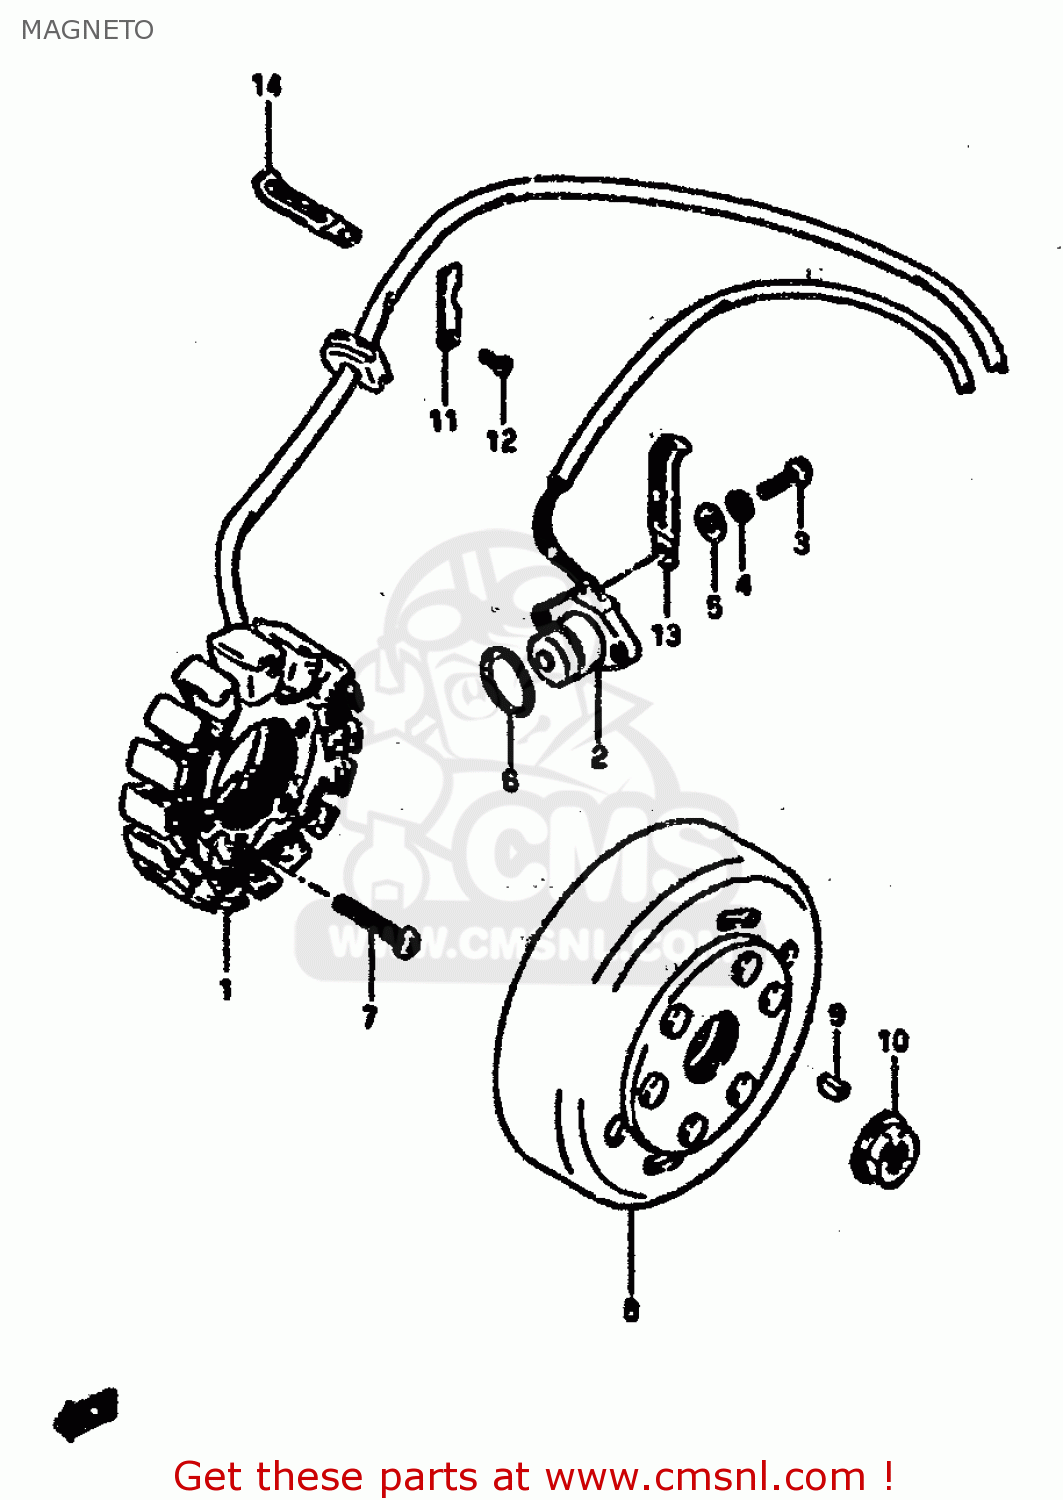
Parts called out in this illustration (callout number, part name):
1	STATOR ASSY
2	COIL ASSY,SIGNAL 1-2
3	SCREW 5X20
4	WASHER,LOCK
5	WASHER,5MM
6	O RING(D:2.5,ID:21)
7	SCREW 6X30
8	ROTOR,FLYWHEEL
9	KEY
10	NUT
11	CLAMP,GENERATOR LEAD WIRE
12	SCREW
13	CLAMP
14	CLAMP
